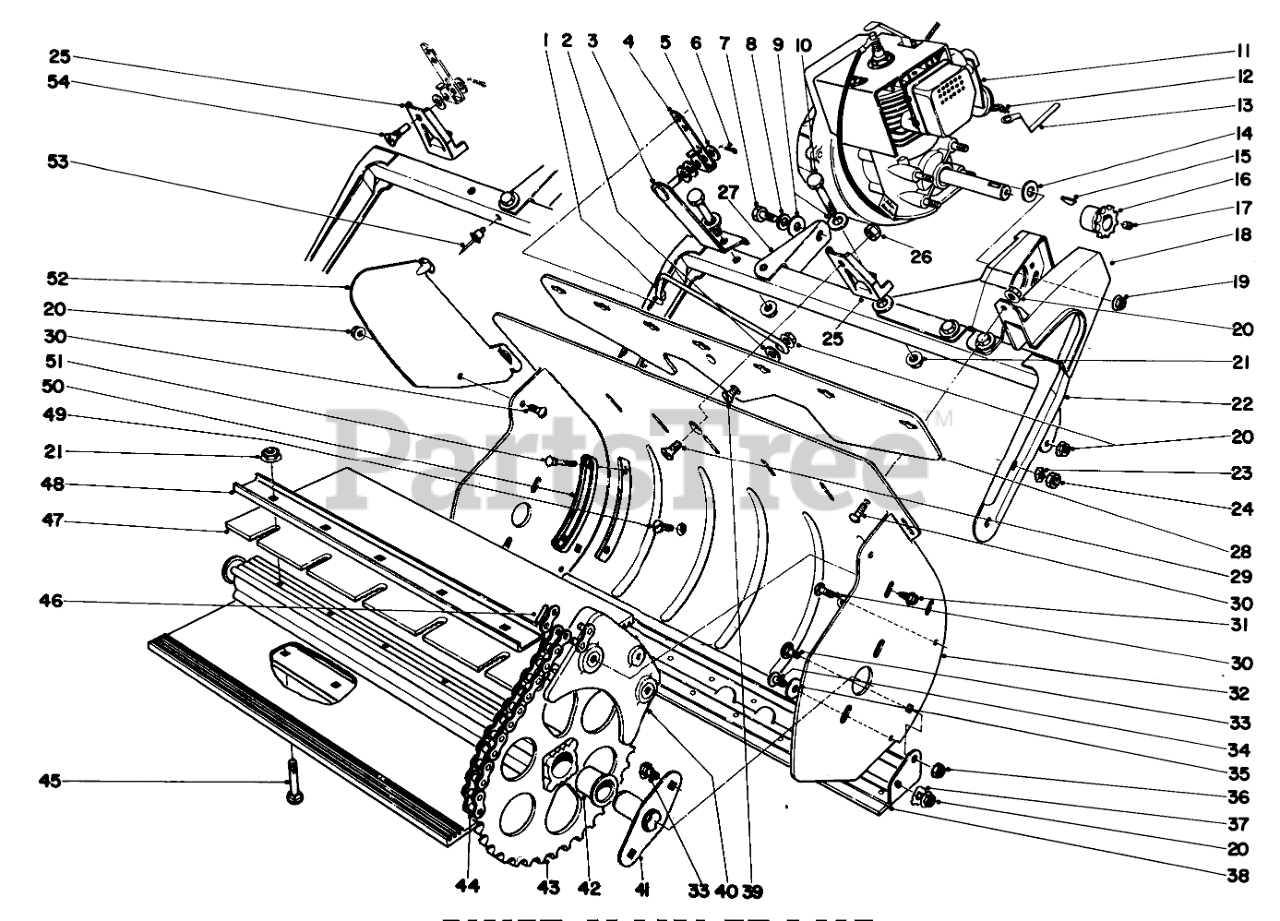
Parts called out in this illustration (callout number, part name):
1	Linkage Vane Adj.
2	WASHER-FLAT
3	Vane Adj. Bracket
4	Bracket-Vane Adj.
5	WASHER-FLAT
6	PIN-COTTER
7	SCREW-HH
8	WASHER-LOCK/EXT
9	WASHER-FLAT
10	SCREW-HH
11	Engine
12	Cotter Pin
13	Choke Strap
14	WASHER-PLAIN
16	SPROCKET
17	SCREW-SET, HSH
18	Chain Guard
19	NUT-HHF
20	NUT-LOCK, FLANGE
21	Nut
22	Frame Assy.
22	Frame Assembly
23	Washer
24	Nut
25	Stiffener
26	NUT-LOCK, NI
27	Bracket
28	Mount-Vane
28	Mount Vane
29	5/16-18X5/8 FLT HD MS
30	SCREW-PTH
31	Screw
32	Housing
33	SCREW-CARRIAGE
34	SCREW-HEAD, PAN
35	Washer
36	NUT-KEPS
37	Washer
38	Skid Assy.
39	10-24X1-1/8 FLT HD MS
40	Stripper
41	Rotor Shaft Assy.
42	Bushing
43	Sprocket & Tube (Incl. Ref. #42)
43	Sprocket & Tube W.A. Incl. #37
44	CHAIN
46	LINK-CONNECTING, NO. 35
47	Blade-Rotor
48	Strap-Reinforcing
48	Reinforcing Strap
50	Handle Plate
51	Bolt-Carriage
52	Vane
53	RIVET
54	Screw
